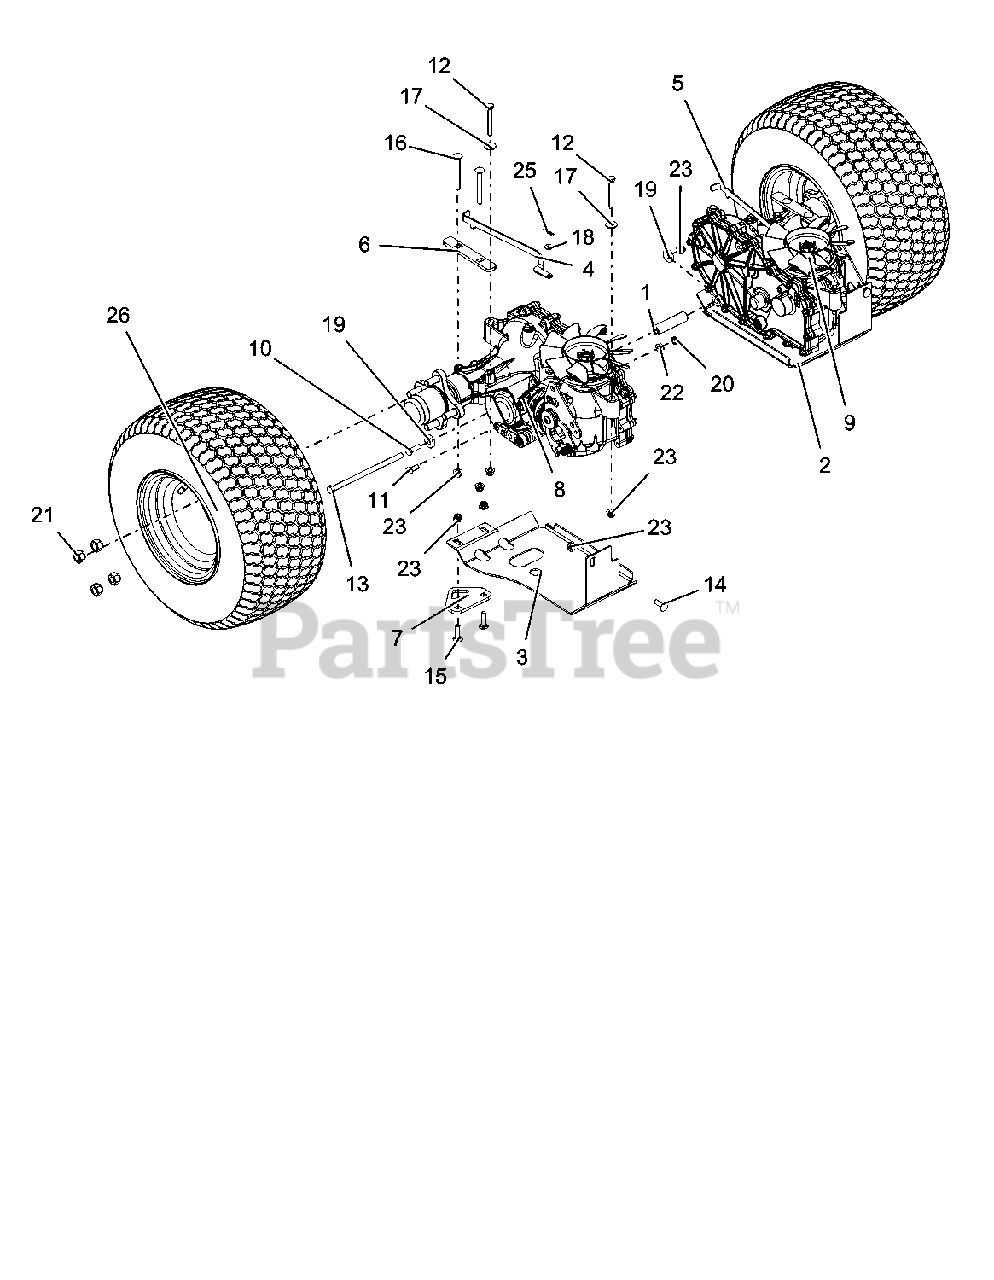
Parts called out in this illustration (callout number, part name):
1	SHAFT, CROSS BRACE
2	PLATE, TRANS SKID
3	PLATE, TRANS SKID
4	BRKT, LH DUMP VALVE
5	BRKT, RH DUMP VALVE
6	DOUBLER, TRANS MNT
7	BRKT, TIE DOWN LOOP
8	TRANSAXLE, RH - ZT31000
9	TRANSAXLE, LH - ZT3100
10	@BLT-HEX .31-18X1.00 GR5 YWZC
11	@BLT-HEX .31-18X.75 GR5 YWZC
12	@BLT-HEX .31-18X2.50 GR5 YWZC
13	@BLT-HEX .38-16X7.00 GR5 YWZC
14	@BLT-RDHDSQNK .31-18X1.00 G5YZ
15	@BLT-RDHDSQNK .31-18X1.25 G5YZ
16	BLT-RDHDSQNK .31-18X3.00 G5YZ
17	@WSHR-FL-STL.38X.875X.083 YWZC
18	@WSHR-FL-STL.281X.62X.065 YWZC
19	WSHR-FL-STL .406X1.00X.188 YWZ
20	@NUT-LK-CTR-JAM .31-18 YWZC
21	WHEEL NUT .500-20 YZ
22	@NUT-SPNLK-FLG .312-18 YWZC
23	@NUT-LK-NYL-FLG .31-18 YWZC
25	PIN-HAIR, ENDRIES #25 YWZC
26	ASM, WHL/TIRE 18X8.50-8
